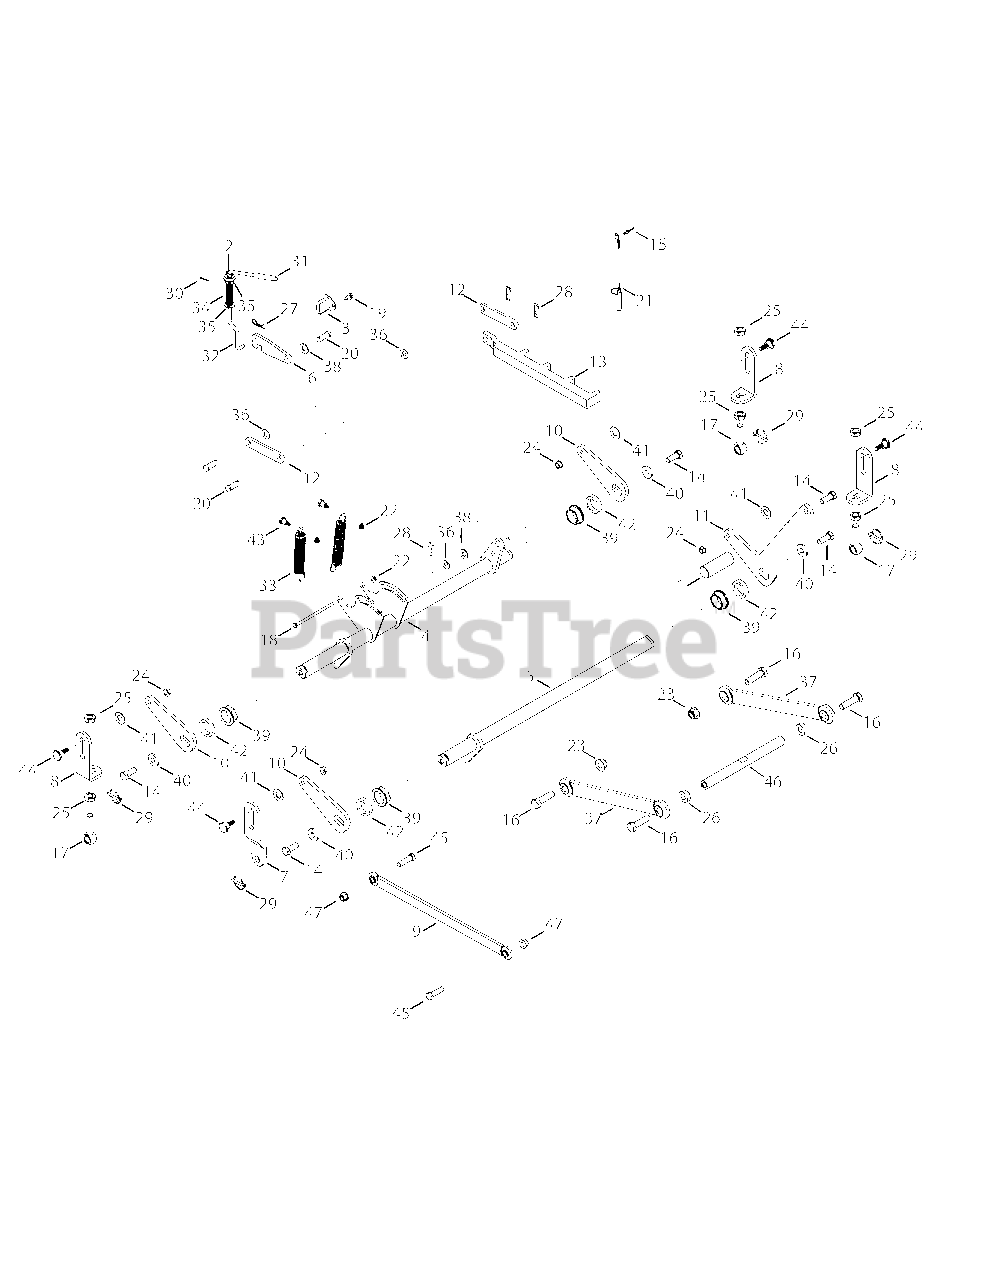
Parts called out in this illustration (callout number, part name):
1	Deck Lift Foot Pedal
2	Bearing, .385 ID
3	Lift Lock Mount
4	Deck Lift Shaft, Rear
5	Deck Lift Shaft, Front
6	Latch Lock Bracket
7	Lift Link Arm
8	Deck Adjustment Lift Link Arm
9	Deck Lift Arm Assembly
10	Deck Lift Bellcrank
11	Deck Lift Foot Pedal
12	Deck Index Link Arm
13	Lift Index Slider Arm
14	Hex Cap Screw, 1/2-13 x 1.25
15	Rivet, 3/16 x .325
16	Hex Cap Screw, 5/8-11 x 2.25
17	Eye Bolt, 5/8-18 x 2.63
18	Hex Cap Screw, 1/4-20 x 5.00
19	Screw, 5/16-18 x .500
20	Clevis Pin, .500 x 1.25
21	Clevis Pin, .438 x 1.5
22	Nut, 1/4-20, Flangelock
23	Nut, 5/8-11, Flangelock
24	Nut, 3/8-16, Flange Centerlock
25	Jam Nut, 5/8-11
26	Spacer, .635 x 1.25 x .445
27	Click Pin, .092 x 1.64
28	Internal Cotter Pin
29	Lynch Pin, .1875
30	Cotter Pin, 3/32 x .750
31	Lift Handle Grip
32	Lift Lock Rod
33	Extension Spring, .969 OD x 6.180
34	Compression Spring, .656 OD x 2.445
35	Bevel Washer, .340 x .872 x .060
36	Washer, .510 x 1.00 x .125
37	Deck Rod Assembly
38	Washer, .510 x 1.00 x .125
39	Hex Flange Bearing
40	Flat Washer, .531 x 2.125 x .250
41	Washer, .640 x 1.25 x .050
42	Spacer, 1.27 x 1.75 x .375
43	Shoulder Screw, .437 x .50, 1/4-20
44	Shoulder Screw, .625 x .442, 3/8-16
45	Hex Cap Screw, 1/2-13 x 1.75
46	Front Lift Link Shaft, Threaded
47	Nut, 1/2-13, Flangelock
